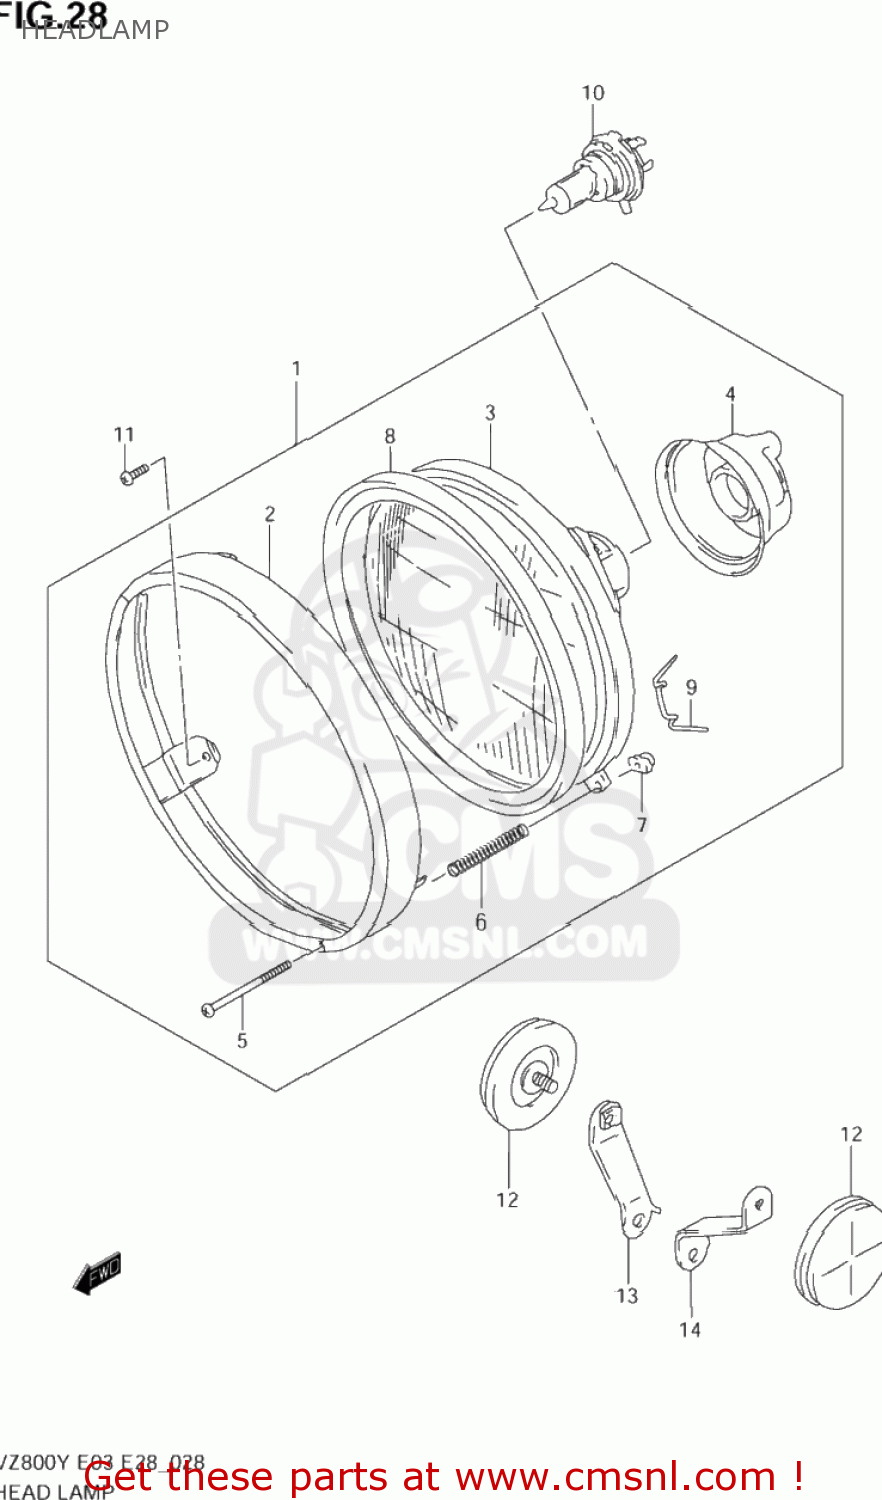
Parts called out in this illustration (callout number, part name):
1	HEADLAMP ASSY
2	RIM ASSY
3	LAMP UNIT
4	COVER,SOCKET
5	SCREW
6	SPRING,ADJUSTING
7	NUT
8	RING
9	SPRING
10	BULB(12V60/55W,H4)
11	SCREW(5X12)
12	REFLECTOR,REFLEX FR
13	BRACKET,FR SIDE RR,R
14	BRACKET,FR SIDE RR,L
